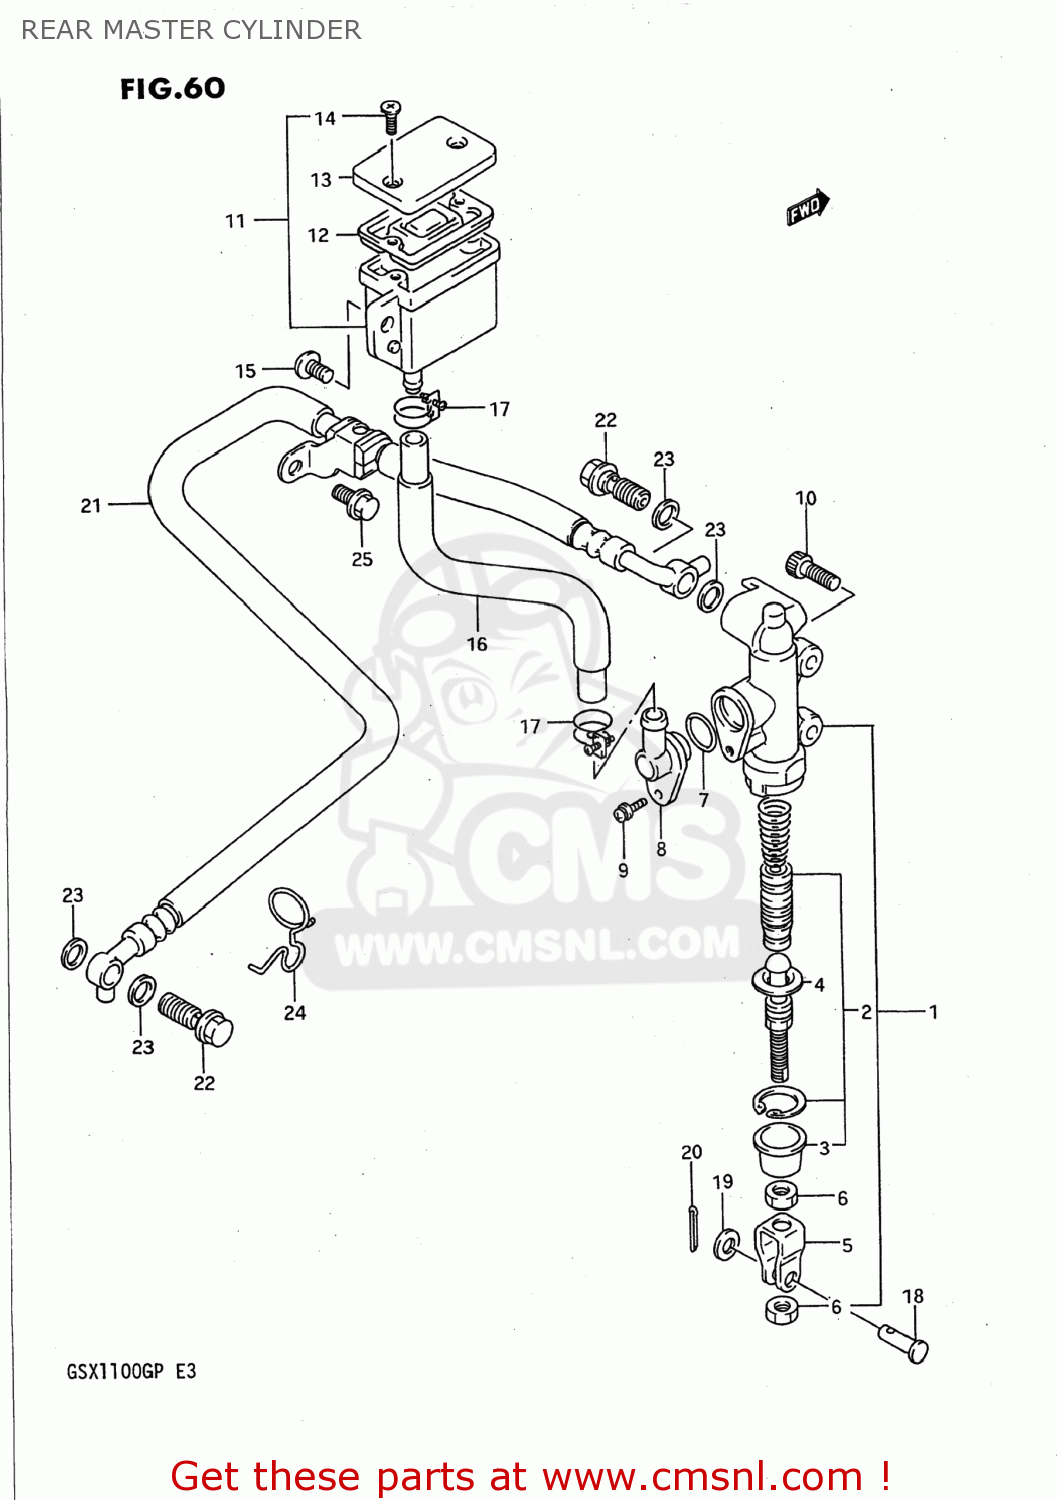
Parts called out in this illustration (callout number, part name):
1	CYLINDER ASSEMBLY,REAR MASTER
2	PISTON/CUP SET
3	BOOT
4	ROD,PUSH
5	YOKE
6	NUT
7	O RING
8	CONNECTOR
9	SCREW
10	BOLT
11	TANK ASSY,RESERVOIR
12	DIAPHRAGM
13	CAP
14	SCREW
15	SCREW 6X12
16	HOSE,RESERVOIR TANK
17	CLAMP
18	PIN
19	WASHER
20	PIN
21	HOSE,REAR BRAKE
22	BOLT UNION
23	WASHER(10X15X1.5)
24	GUIDE,BRAKE HOSE
25	BOLT
